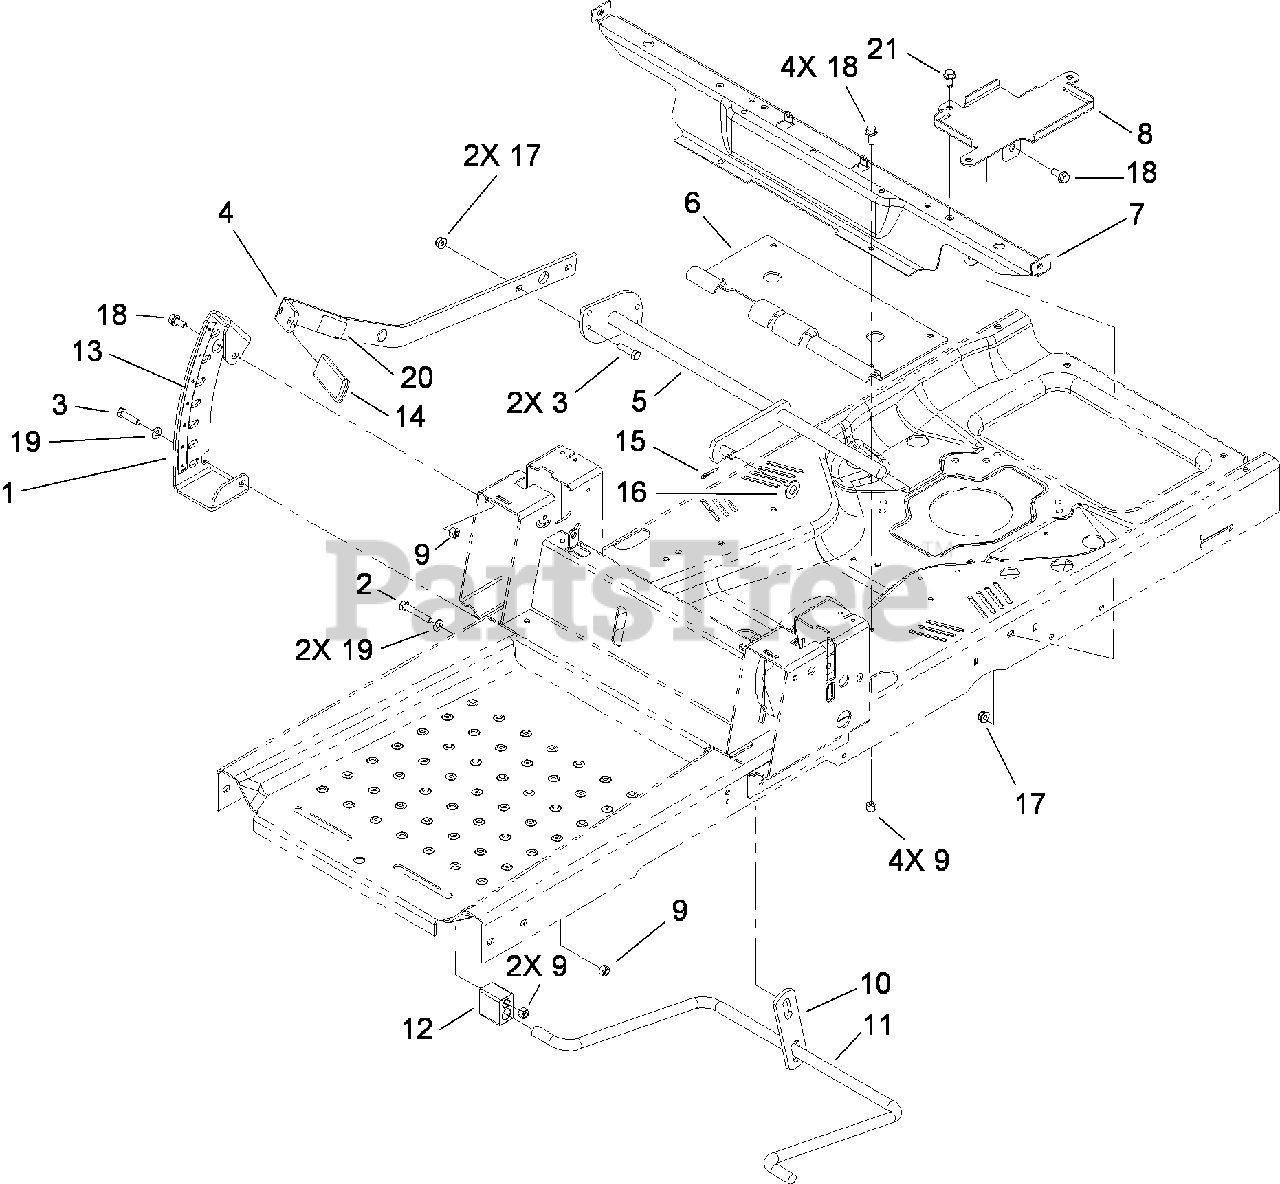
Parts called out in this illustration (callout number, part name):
2	SCREW-HH
3	SCREW-HH
4	LIFT ARM ASM
5	LIFT LEVER ASM
7	BRACKET-SEAT/PODS
8	TRAY-BATTERY
9	NUT-LOCK, NI
10	LINK-LIFT
11	ARM-LIFT, REAR
12	BLOCK-PIVOT
13	DECAL-HOC
14	GRIP-LEVER, LIFT
15	PIN-COTTER
16	WASHER-FLAT
17	NUT-FLANGE, NI
18	SCREW-HHF
19	WASHER-FLAT
21	SCREW-HWH
